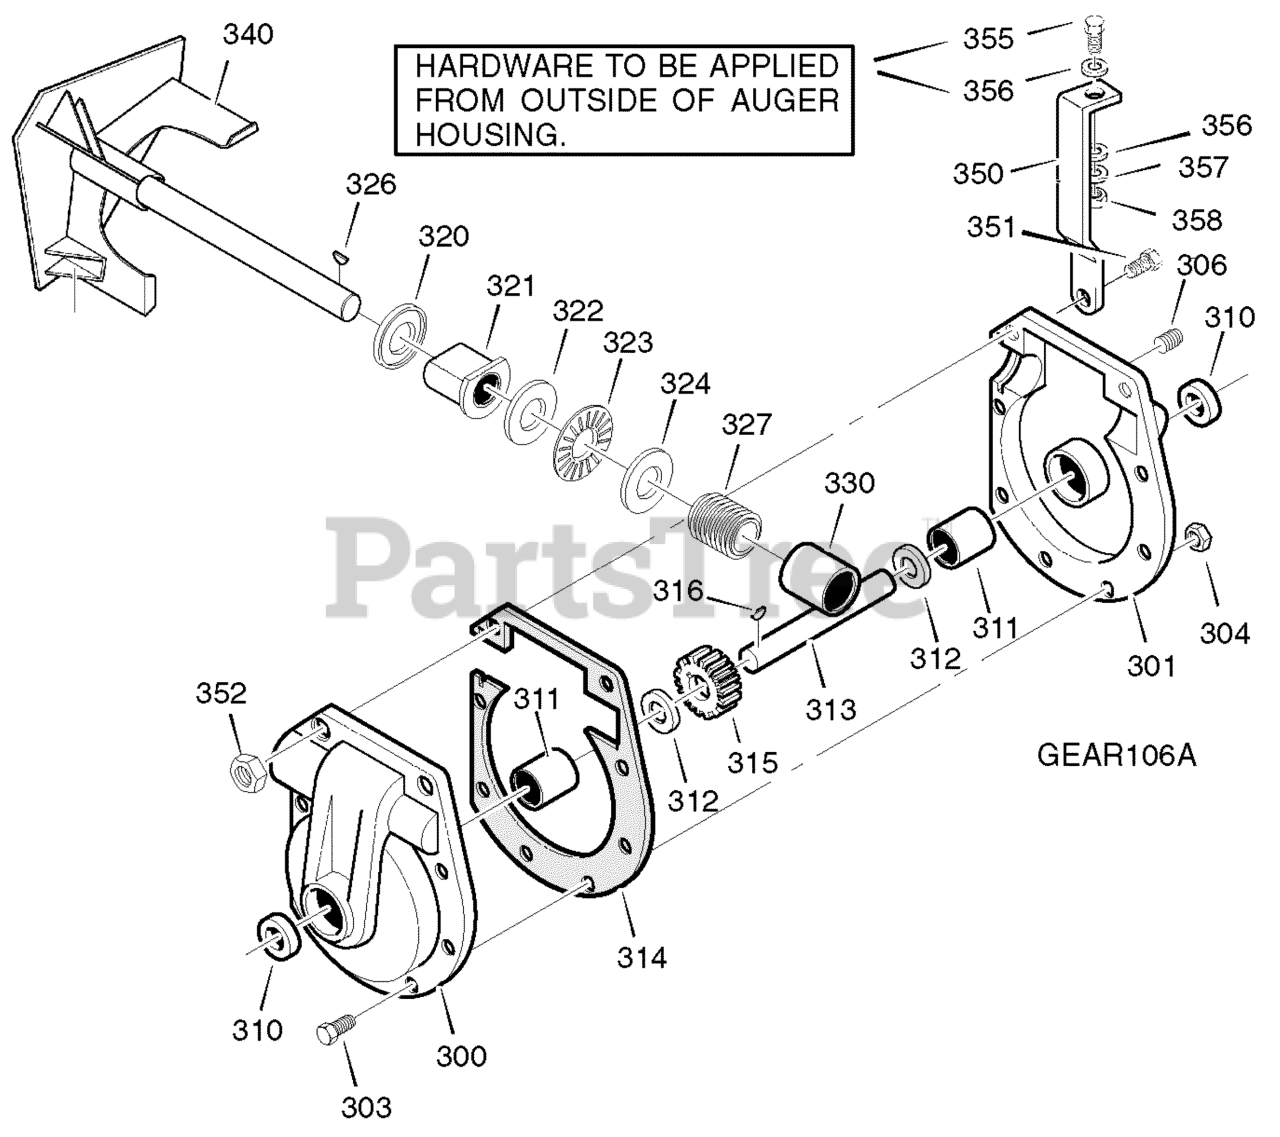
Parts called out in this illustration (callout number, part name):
300	CASE, GEAR, RH
301	CASE, GEAR, LH
303	SCREW, 5/16-24 x 1.00
304	NUT, 5/'16-24
305	SCREW, 5/16-24 x 1.50
306	PLUG, PIPE 0.25-18
310	SEAL, OIL
311	BEARING, SLEEVE
312	WASHER, FLAT
313	SHAFT, AUGER OUTPUT
314	GASKET, GEAR BOX
315	WORM GEAR
316	KEY, WOODRUFF #91
320	RING, QUAD 0.924 ID
321	BEARING, FLANGE
322	WASHER, FLAT
323	BEARING, ROLLER
324	WASHER, FLAT
326	KEY
327	GEAR, WORM
330	BEARING, SLEEVE
350	BRACE, GEAR BOX
351	SCREW, 5/16-24 x 1.75
352	NUT, HEX 5/16-24
355	SCREW, 5/16-18 x 1.25
356	WASHER, FLAT
357	WASHER, SPTLK
358	NUT, REGHEX 5/16-18
